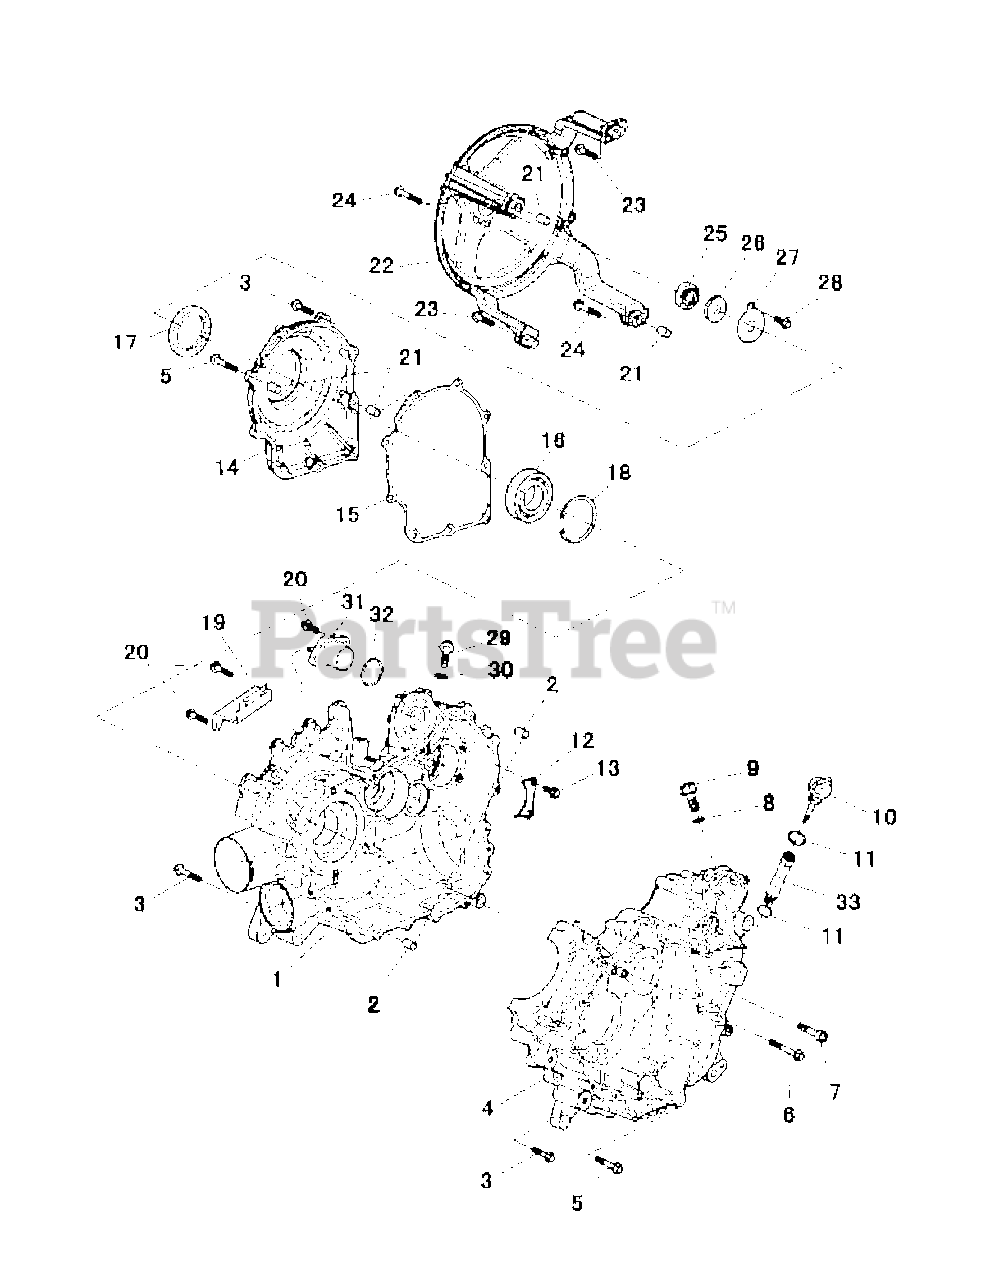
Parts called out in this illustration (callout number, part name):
1	Crankcase-Complete RH
3	Flangebolt M6X30
4	Left Crankcase Comp
5	Flangebolt M6X40
6	Flangebolt M6X55
7	Screw-Cylinder M8 X 40 Inner
8	Aluminum Washer
9	Screwm 14X1.5X16
10	Gauge-Oil Level
11	O-Ring
12	Press Plate-Main Shaft Bearing
13	Flangebolt M6X16
14	Outer Cover-Bearing Seat
15	Seal Washer-Bearing Seat
17	Oil Seal
19	Exhaust Pipe Support
22	Protection cover bracket, Cluth
23	Flange Bolt M6X32
24	Flange Bolt M6X40
25	Bearing-62012Z
27	Oil Pressure Plate
28	Flangebolt M6X12
29	Flange Bolt M10 X 1.25 X 16
31	Gear Show-Asm
32	O-Ring 29.6X2.4
33	Extended Oil Dipstick Pipe
